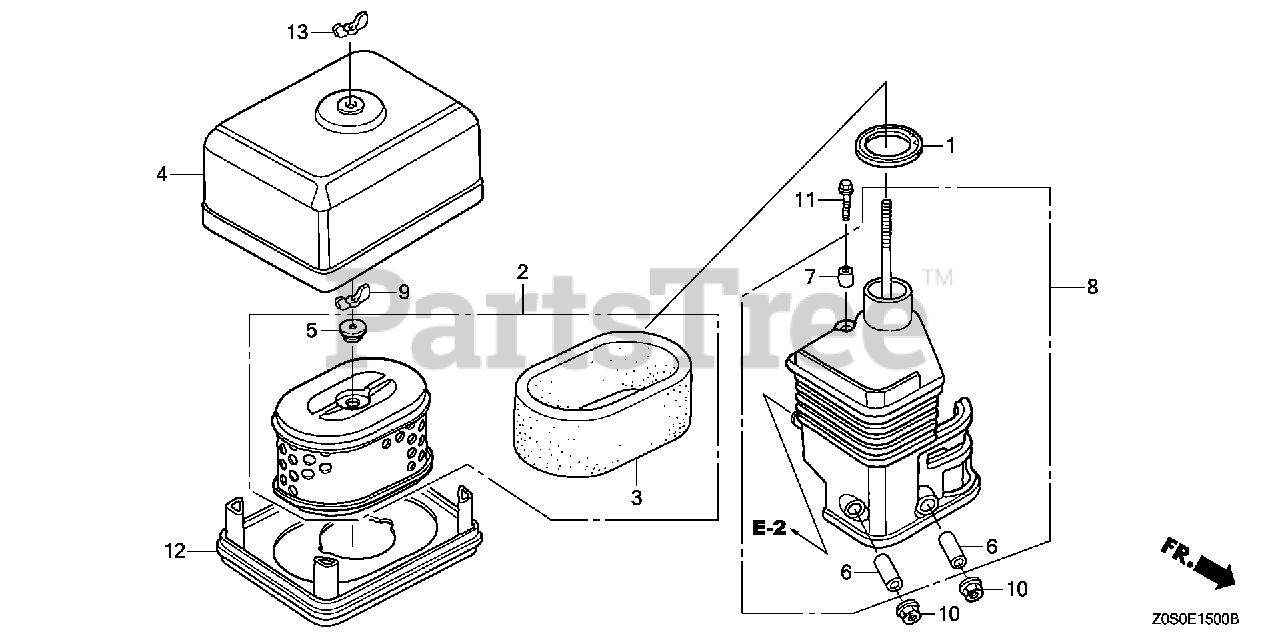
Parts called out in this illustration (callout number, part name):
1	GASKET, ELBOW
2	ELEMENT, AIR CLEANER (DUAL)
3	FILTER (OUTER)
4	COVER, AIR CLEANER (DUAL)
5	GROMMET, AIR CLEANER
6	COLLAR, AIR CLEANER
7	COLLAR B, AIR CLEANER
8	ELBOW, AIR CLEANER
9	NUT, TOOL BOX SETTING
10	NUT, FLANGE (6MM)
11	BOLT, FLANGE (6X20)
13	NUT, TOOL BOX SETTING
